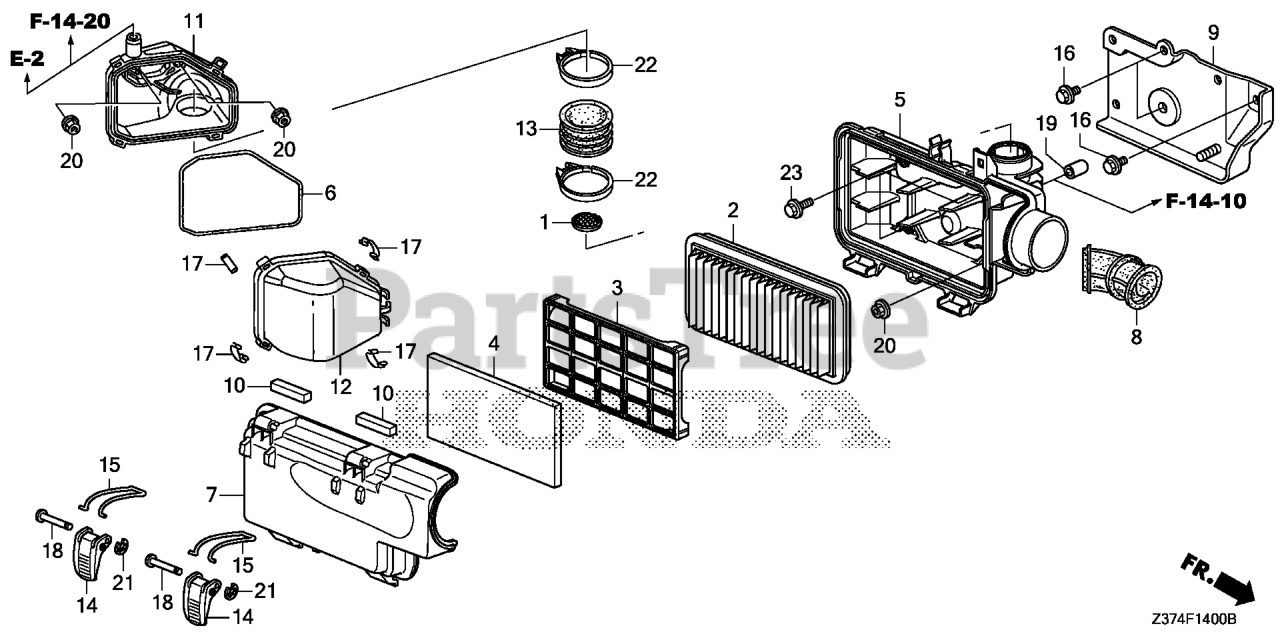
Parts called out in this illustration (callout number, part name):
1	TRAP, FLAME
2	ELEMENT, AIR CLEANER
3	GRID, AIR CLEANER
4	FILTER (OUTER)
5	HOUSING, AIR CLEANER
6	SEAL, AIR CLEANER CHAMBER
7	COVER, AIR CLEANER
8	RUBBER, AIR CLEANER
9	BRACKET, AIR CLEANER
10	SEAL, AIR CLEANER
11	HOUSING, AIR CLEANER CHAMBER
12	COVER, AIR CLEANER CHAMBER
13	TUBE, AIR CLEANER CONNECTING
14	LEVER, FASTENER
15	SPRING, FASTENER WIRE
16	BOLT, FLANGE (6X14)
17	CLAMP, CASE
18	PIN (5X44.5)
20	NUT, FLANGE (6MM)
21	E-RING (4MM)
22	BAND, AIR CLEANER CONNECTING TUBE (54)
23	BOLT, FLANGE (6X22)
